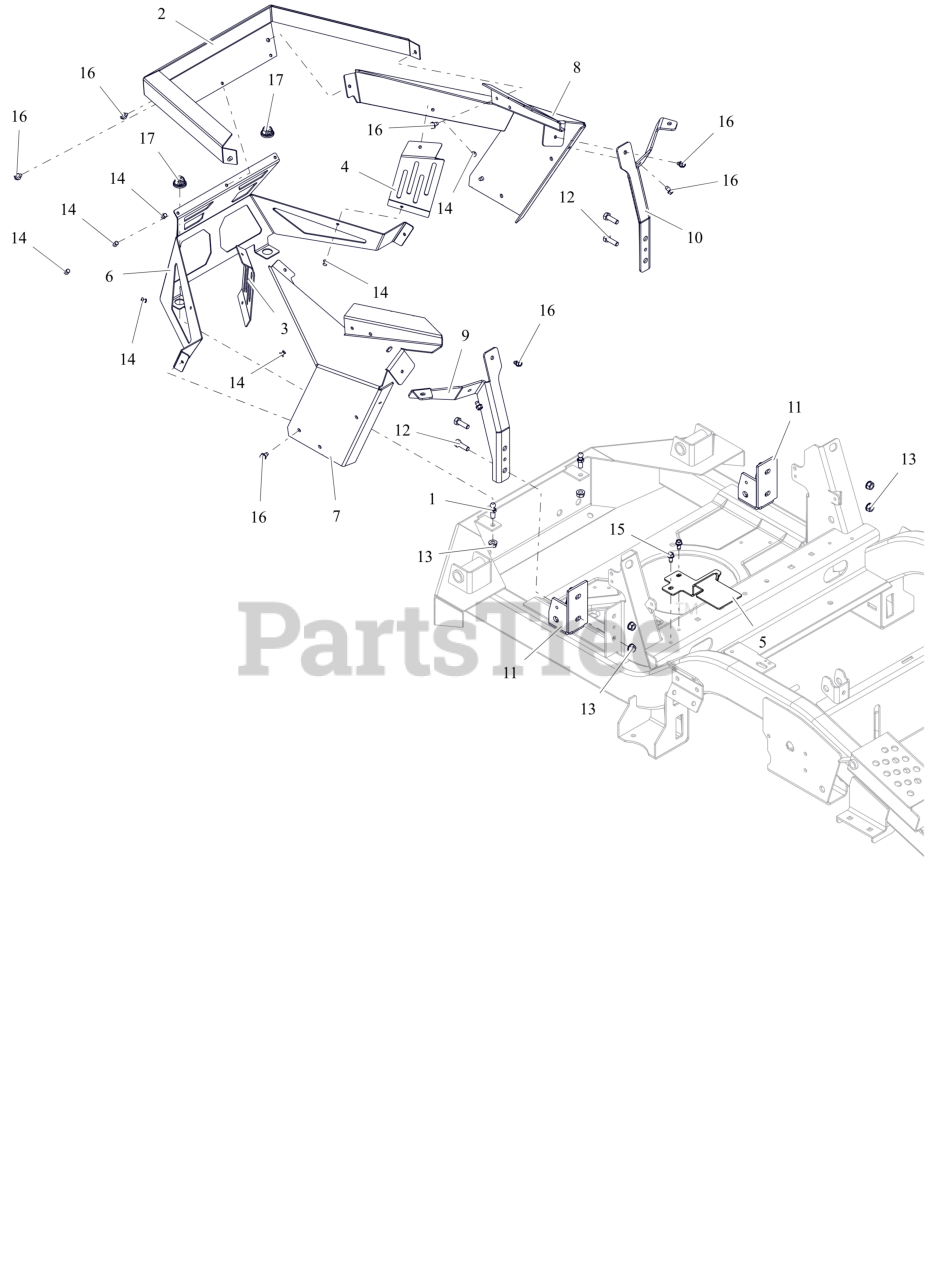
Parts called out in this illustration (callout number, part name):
1	STUD- BALL
2	GUARD,ENGINE WRAP
3	SHIELD,RH ENGINE GUARD VALVE
4	SHIELD,LH ENGINE GUARD VALVE
5	GUARD, TRANSAXLE FAN RH (BLACK)
6	GUARD, ENGINE
7	PANEL, RH REAR FENDER MOUNT
8	PANEL, LH REAR FENDER MOUNT
9	BRKT, RH FENDER MTG (ORANGE)
10	BRKT, LH FENDER MOUNT (ORANGE)
11	BRKT, ROPS SUPPORT (BLACK)
12	BLT, HEX .31-18X1.00 G8 ZCC
13	NUT,LK-CTR-FLG .31-18 GF ZCC
14	RIVET, .1875 AL/AL .126-.250
15	SCR-TAP .25-20X.50 HWH ZCC
16	SCR,TAP .25-20X.375 HWH TR ZCC
17	GROMMET, 10MM BOLLHOFF
